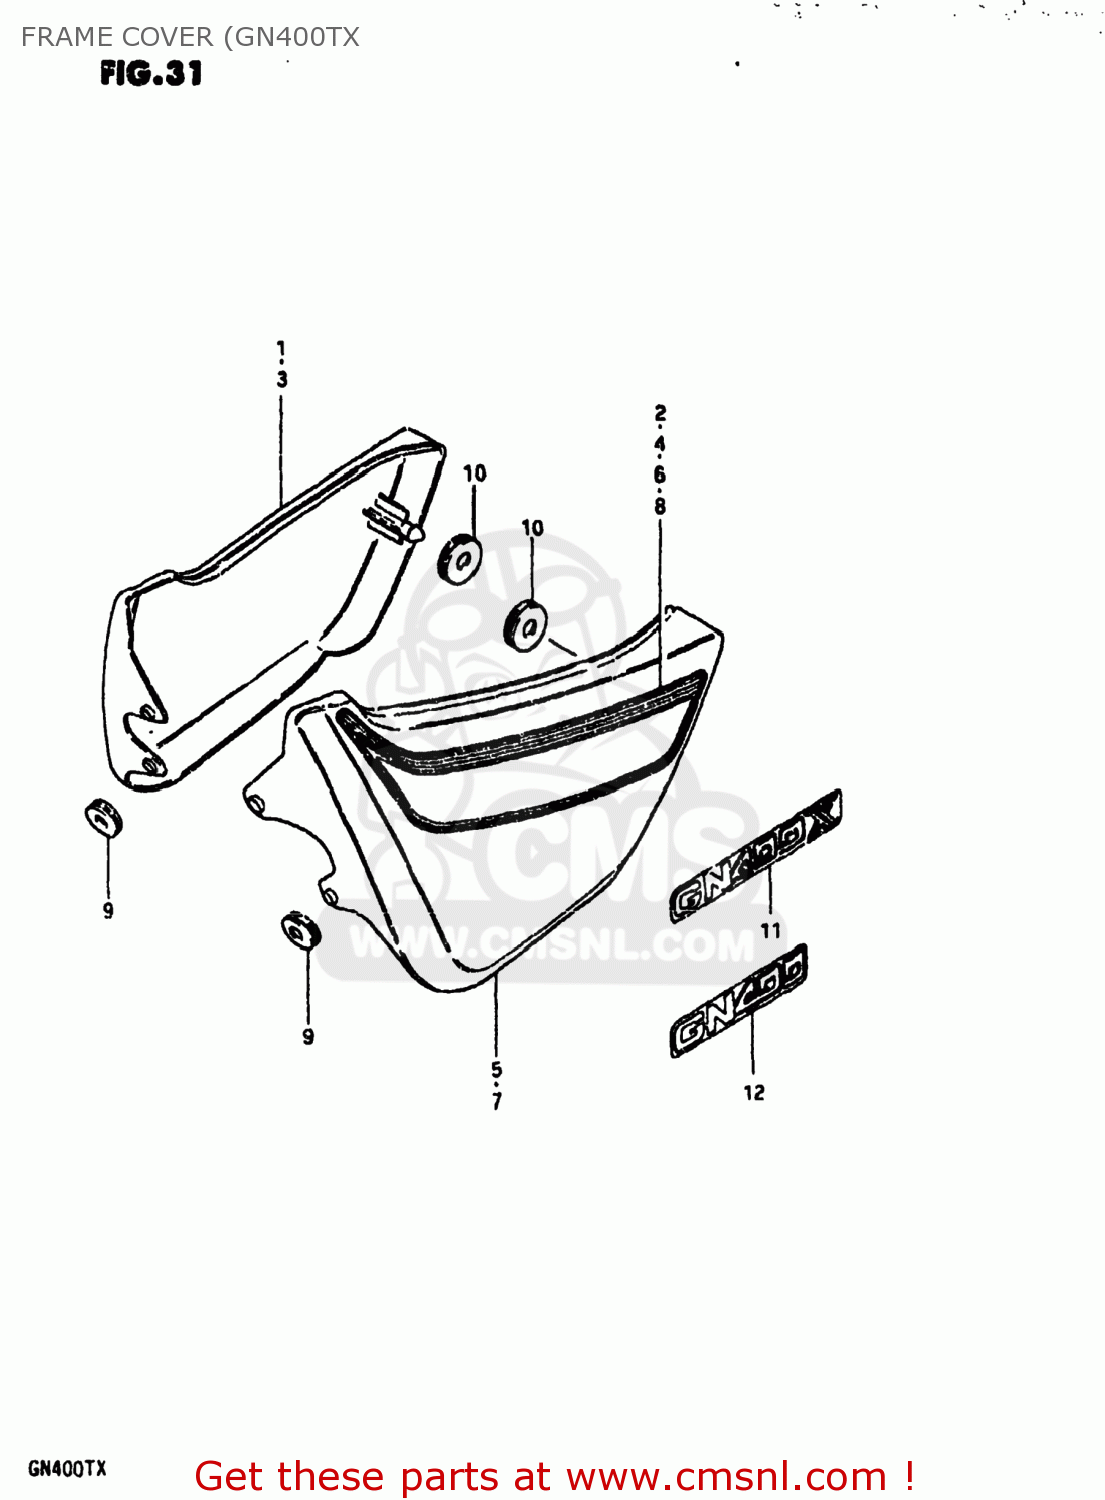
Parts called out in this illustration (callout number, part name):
1	COVER,FRAME,RIGHT
2	TAPE SET,FRAME COVER
3	COVER,FRAME,RIGHT
4	TAPE SET,FRAME COVER
5	COVER,FRAME,LEFT
6	TAPE SET,FRAME COVER
7	COVER,FRAME,LEFT
8	TAPE SET,FRAME COVER
9	CUSHION
10	CUSHION
11	EMBLEM
12	EMBLEM (GN400)
